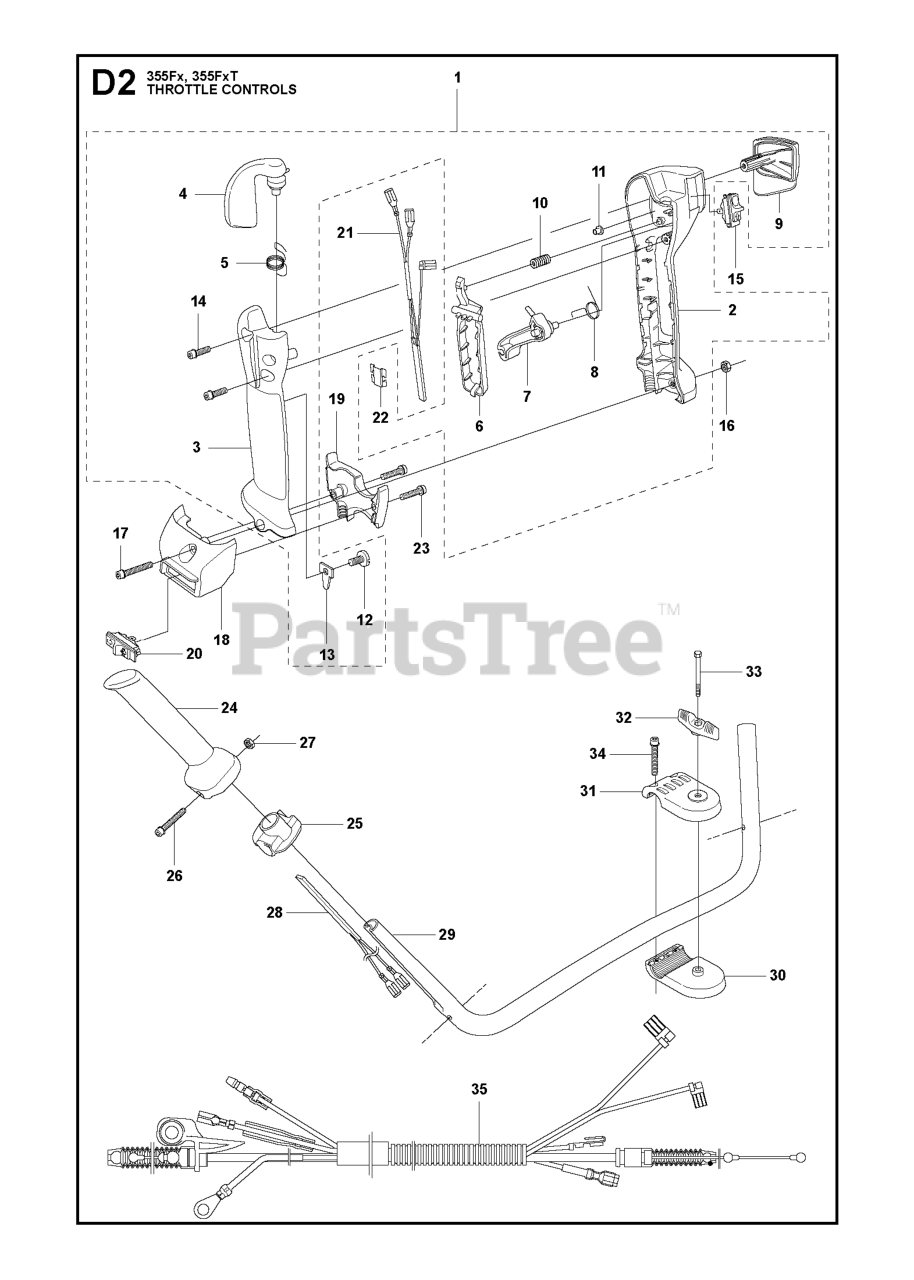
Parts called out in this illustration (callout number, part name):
1	THROTTLE HANDLE
2	HANDLE
3	HANDLE
4	THROTTLE TRIGGER
5	RP SPRING
6	THROTTLE LOCK
15	STOP BUTTON
16	NUT M6M M5
17	SCREW
18	HOLDER
19	HOLDER
20	SWITCH (G)
21	HEATING ELEMENT
23	SCREW
27	NUT M6M M5
28	HEATING ELEMENT
29	%HANDLE
30	HANDLE HOLDER LOWER
31	HANDLE HOLDER UPPER
33	SCREW 6X70
35	WIRING
